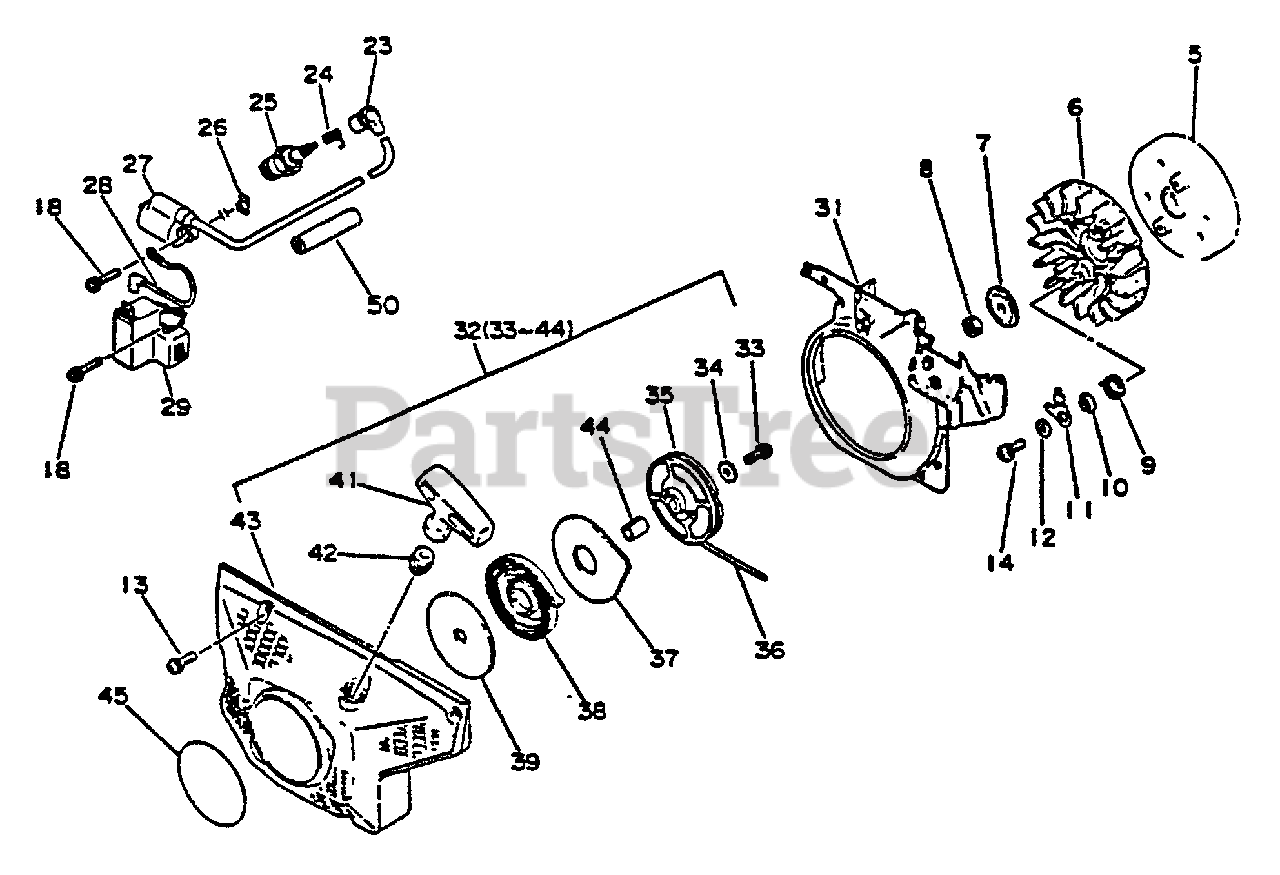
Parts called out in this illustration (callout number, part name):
5	FLYWHEEL
6	FAN
7	WASHER 8.2×31×0.8
9	SPRING, RETURN
10	SPACER
11	PAWL, STARTER
12	WASHER 5.5×12×0.8
13	SCREW 5×20
14	SCREW - 5×25
18	SCREW - 4×20
23	CAP, SPARK PLUG
24	TERMINAL, SPARK PLUG
25	SPARK PLUG - BPM7A
27	COIL, IGNITION
28	KEY, WOODRUFF
29	COIL, IGNITION
31	SHIELD, FAN
32	STARTER ASSY
33	SCREW 5×14
34	WASHER 5.2×16×1.0
35	REEL, ROPE
36	ROPE, STARTER 4.0×950
37	PLATE, STARTER
38	SPRING, RECOIL
39	PLATE, STARTER
41	GRIP, STARTER
42	GUIDE, ROPE
43	CASE, STARTER
45	LABEL - ECHO
50	TUBE
